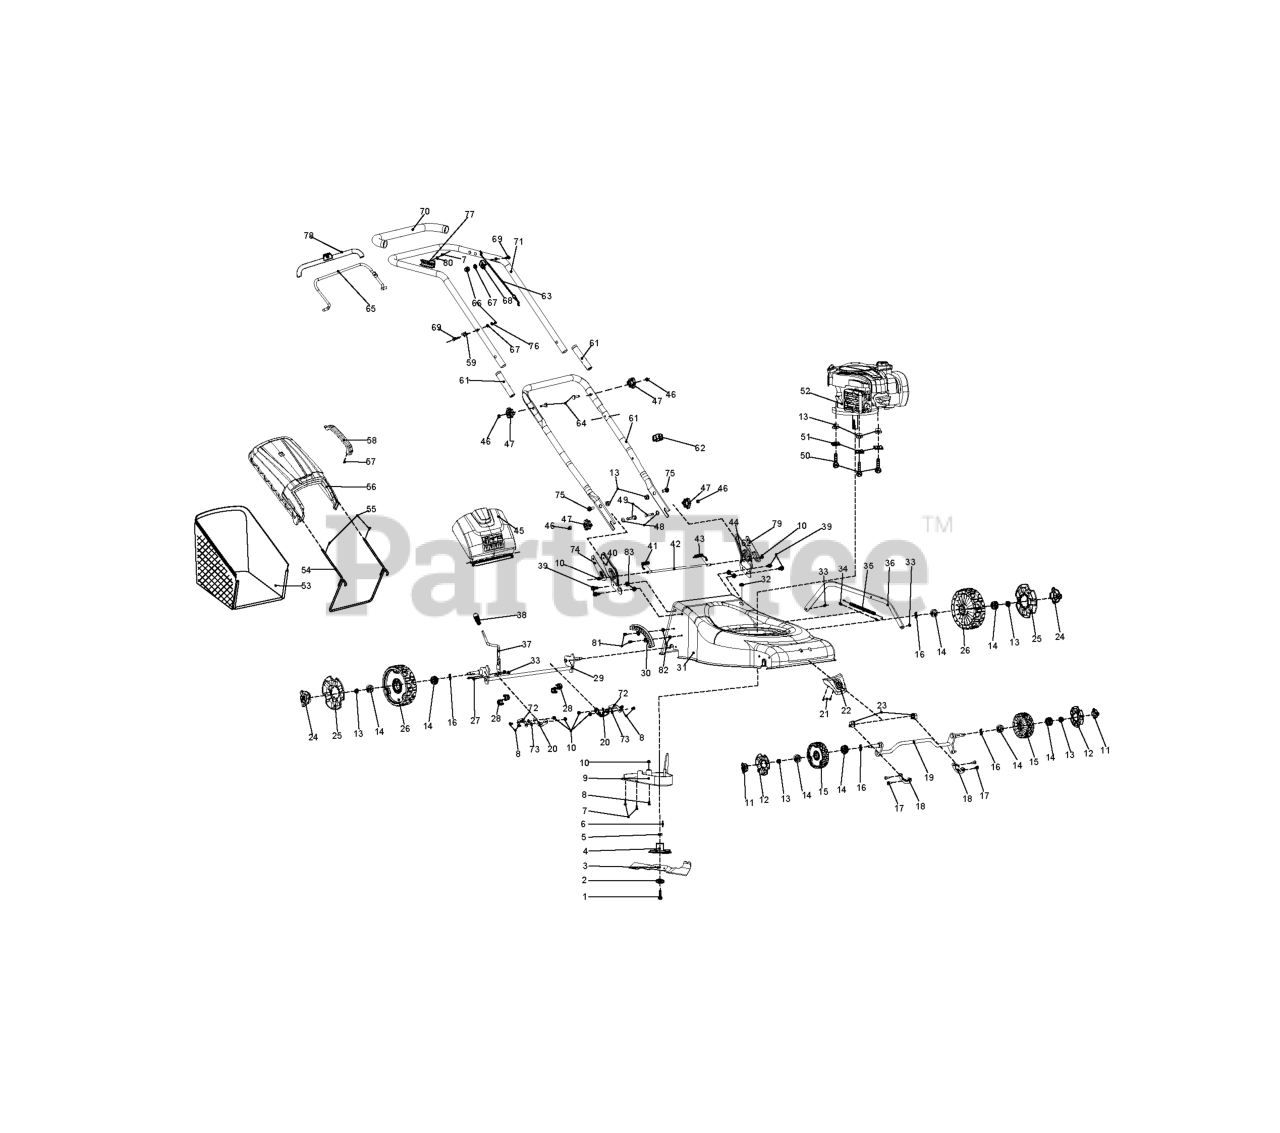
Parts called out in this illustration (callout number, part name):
8	SCREW M6*16 #26800204601
10	LOCK NUT M6,GB/T6187.1-2000 #2
11	WHEEL COVER 6" #25340700101
13	LOCKING BOLT M8,GB6187.1 #2680
16	WASHER Ï?12 #26800706202
20	FIXING PLATE #26300124401
24	WHEEL COVER 8" #25341000101
25	WHEEL COVER 8" #25341100101
26	WHEEL #25341300101
27	WASHER M6*14 #26800203001
28	COVER AXLE #25235300101
30	SEGMENT #25214200102
33	LOCKING BOLT M6,GB889.1 #26800
34	TUBING #29000300101
35	SPRING #26801103903
37	HANDLE ASSY
38	KNOB HEIGHT ADJUSTMENT #25341
39	BOLT M8*16 #26800606401
40	BRACKET RH
41	SPRING #26801125501
43	BRACKET #26801125401
46	HEXAGON NUT #26800502301
47	KNOB #25341500101
48	SPACER RING
53	GRASSBAG #25100173001
54	BRACKET #26300299201
56	COVER GRASS CATCHER #253417001
57	SCREW ST4.8*19,GB845 #26800104
58	HANDLE #25341800101
62	HOLDER CABLE
72	FIXING PLATE #26300314601
73	O-RING #25100175201
74	PLATE RIGHT
79	PLATE LEFT
